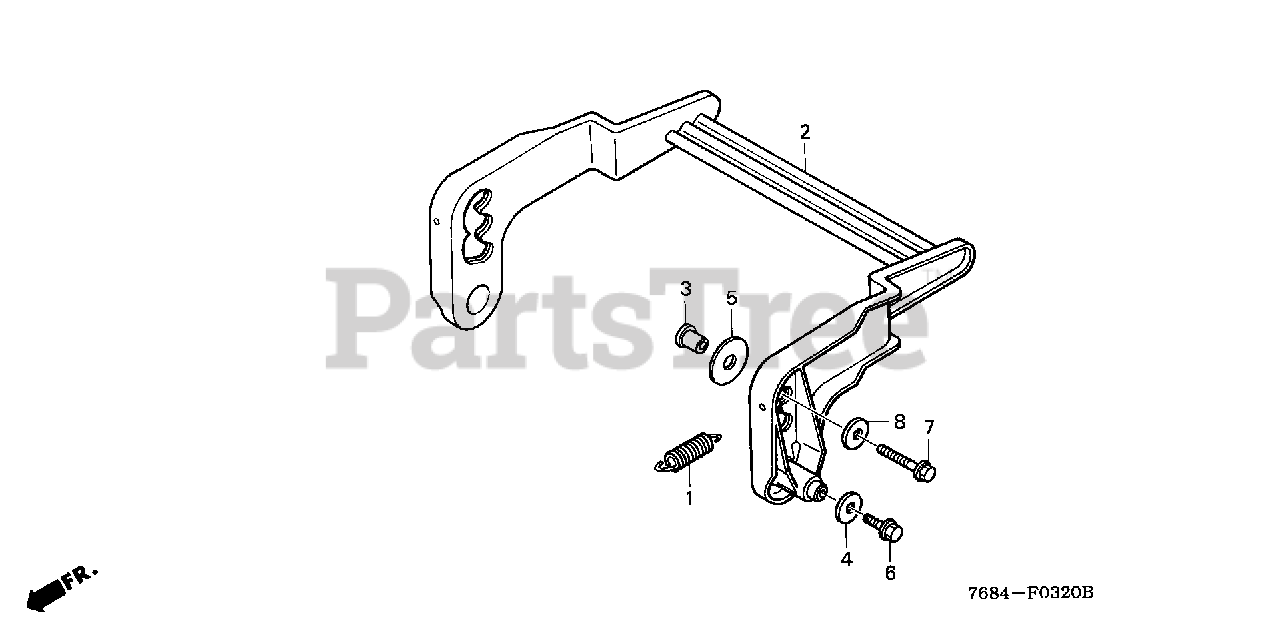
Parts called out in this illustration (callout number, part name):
1	SPRING, HEIGHT ADJUSTING
2	PLATE, HEIGHT ADJUSTING
3	COLLAR, HEIGHT ADJUSTING
4	WASHER, PLAIN (8X23X3.2)
5	WASHER, PLAIN (12MM)
6	BOLT, FLANGE (8X14)
7	BOLT, FLANGE (8X30)
8	WASHER, PLAIN (8X23X3.2)
